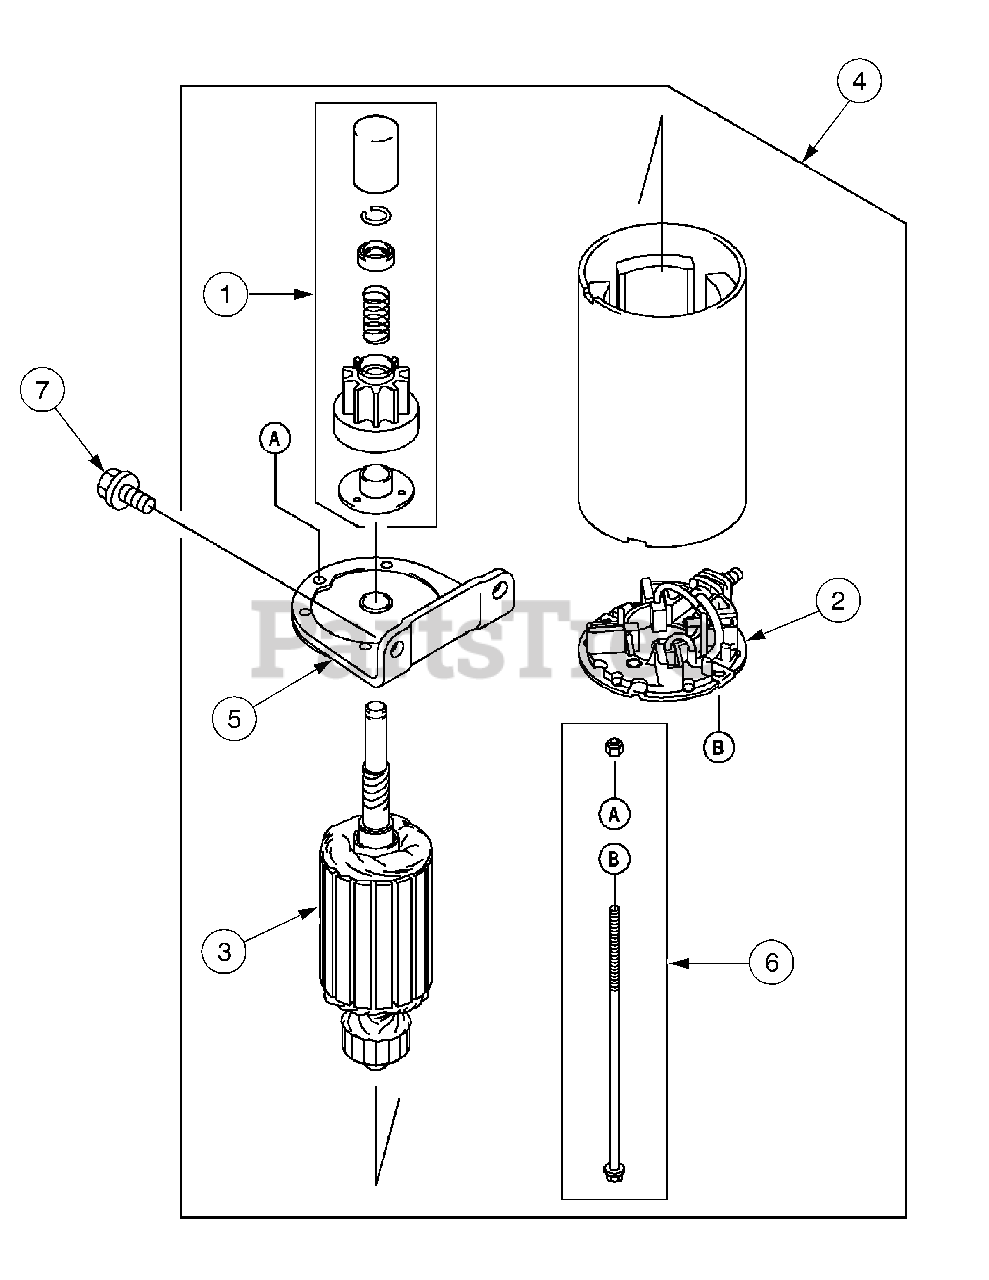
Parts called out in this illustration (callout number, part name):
1	Gear Assembly
2	Brush
4	Starter Assembly
5	Bracket
7	Bolt, Flanged
